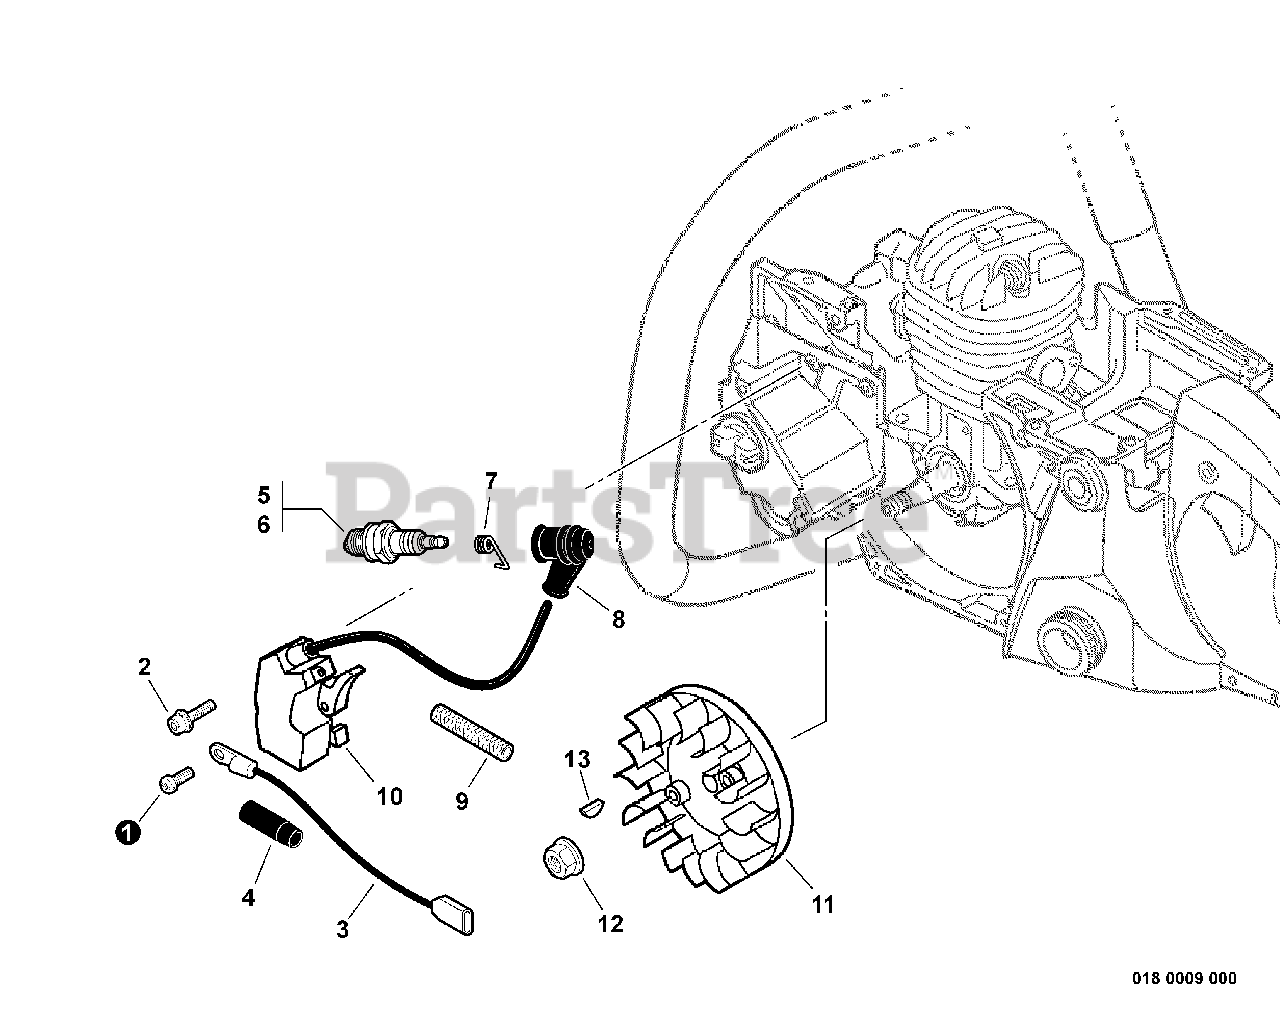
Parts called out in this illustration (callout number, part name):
1	SCREW - 4X6
2	SCREW - 4X30
3	LEAD - GROUND
4	BOOT, CONNECTOR
5	SPARK PLUG -- BPM-8Y
6	SPARK PLUG -- BPMR-8Y
7	TERMINAL, SPARK PLUG CAP
8	CAP, SPARK PLUG
9	TUBE, INSULATOR
10	COIL, IGNITION
11	FLYWHEEL
12	NUT - 8 -- FLANGE
